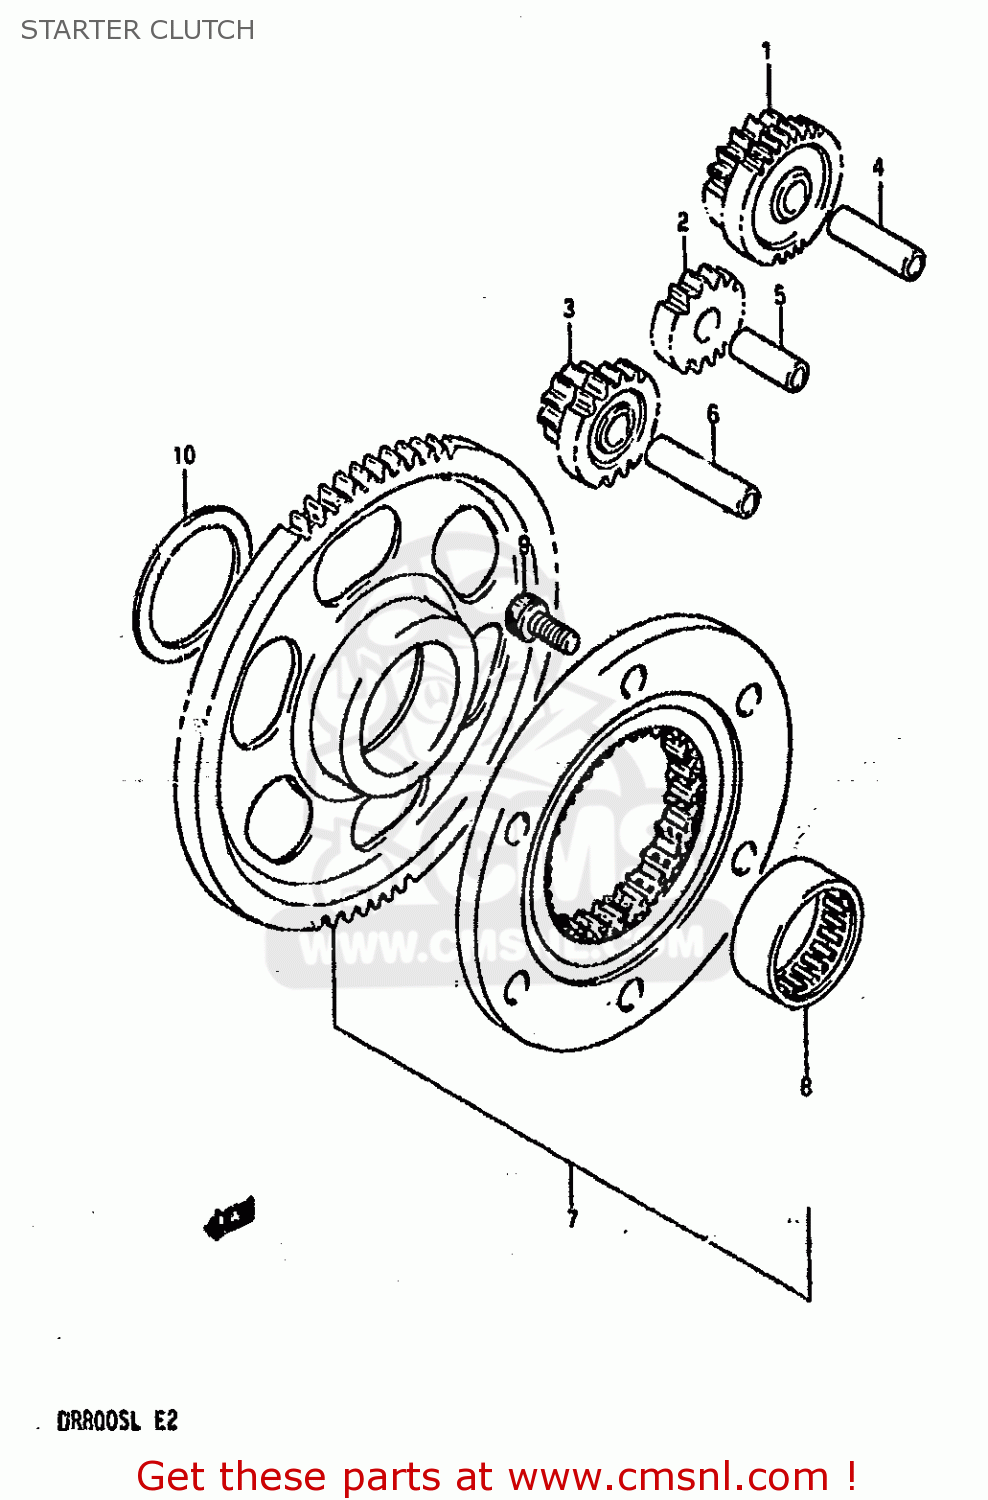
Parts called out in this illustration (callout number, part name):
1	GEAR,STARTER IDLE,NO.1
2	GEAR,STARTER IDLE,NO.2
3	GEAR,STARTER IDLE,NO.3
4	PIN
5	PIN
6	PIN
7	CLUTCH SET,STARTER
8	BEARING(35X43X18)
9	BOLT
10	WASHER
